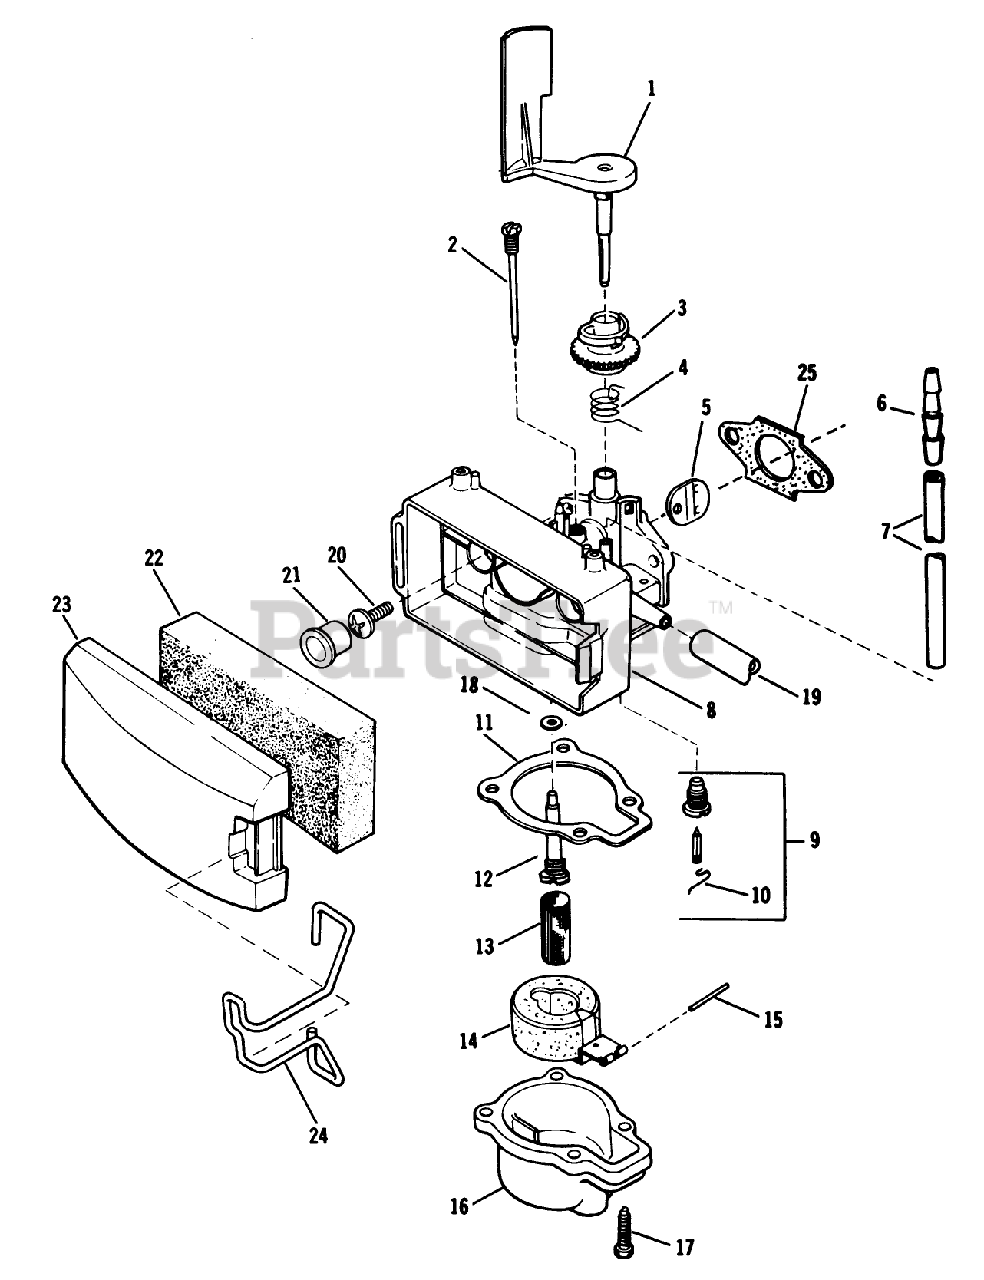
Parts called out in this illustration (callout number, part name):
2	NEEDLE ADJ. AY S
3	COLLAR-ADJUST, AIRVANE
4	SPRING-THRO. S
5	DISC S
6	REDUCER-CONNECTOR
7	TUBING S
8	CARB BODY S
12	NOZZLE S
13	FILTER-FUEL VS
17	SCREW-HH
18	WASHER
20	SCREW
24	RETAINER-COVER, FILTER
25	GASKET CARB S
